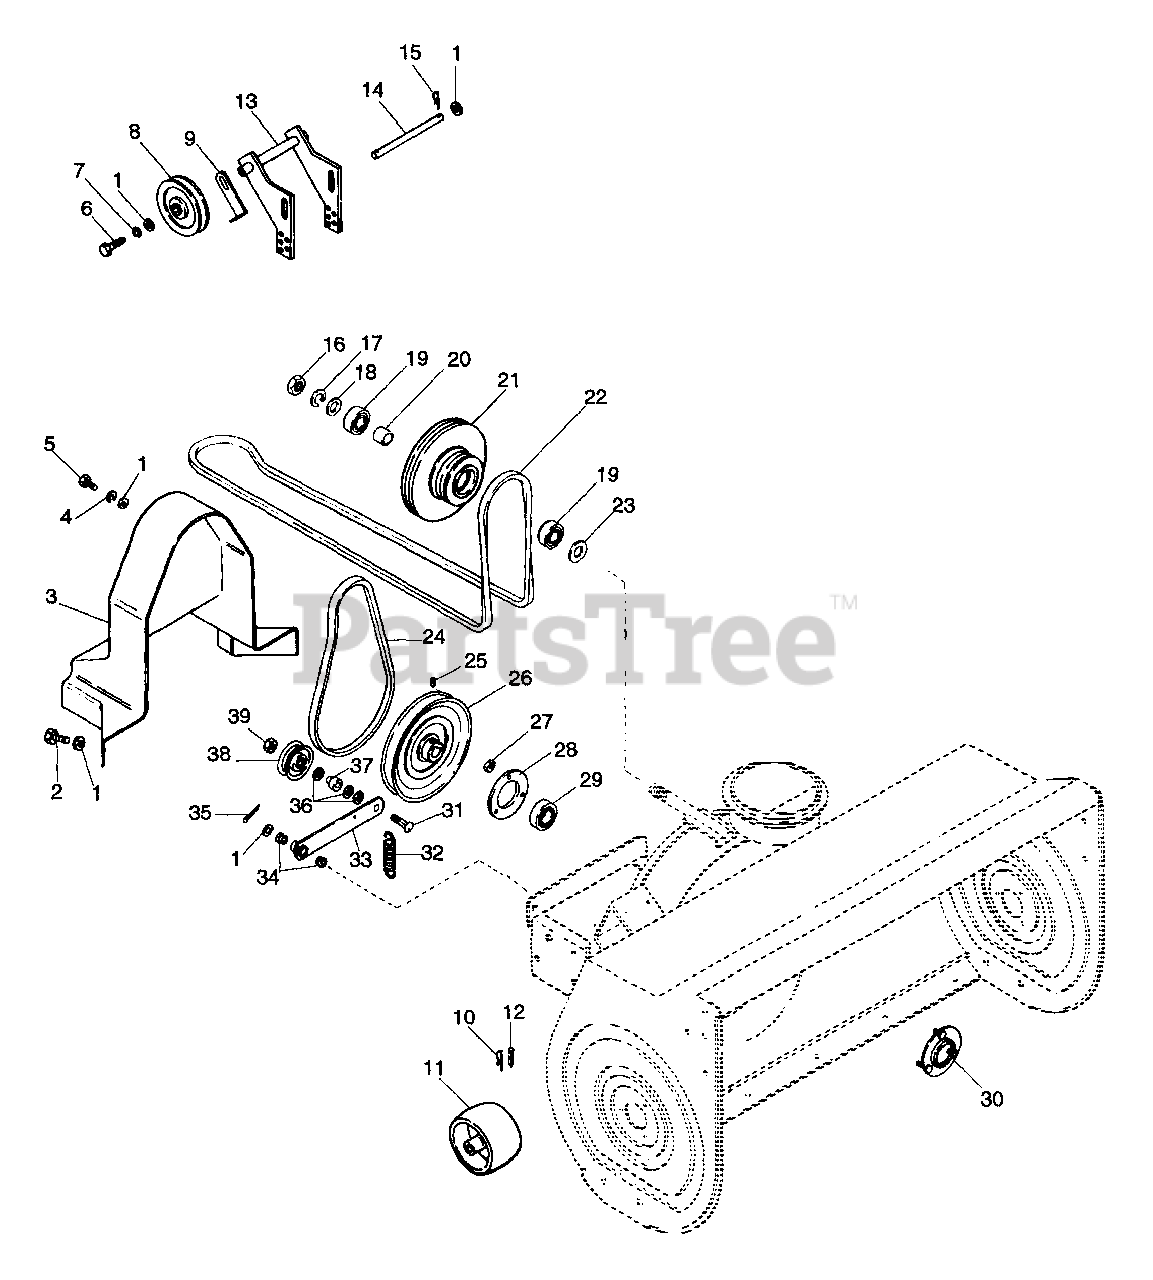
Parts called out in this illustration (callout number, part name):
1	WSHR-FL-STL .382X.812X.062
2	SCR-TAP .375-16X .50 HWH PL TR
3	BELT GUARD
4	WSHR-LK .312X.097 PL HVY
5	BLT-HEX .31-18X.75 PL GR5
6	BLT-HEX .38-16X1.50 PL GR2
7	WSHR-LK .375X.094 MED PL
8	IDLER-V 4.00 X .38 NWHAMSHR
9	BELT RETAINER
10	PIN-HAIR INT .08X.38X1.42 YWZC
12	PIN-COTR .09X.75 PL
13	IDLER BRACKET
15	PIN-HAIR INT .08X.18X1.18
16	NUT-JAM .75-10 PL
17	WSHR-LK-INT .750X.050 MED
18	WSHR-FL-STL .781X1.250X.059 PL
19	BRG-BALL .750X1.781X.61
20	SPACER 1.00 X .770/.760 X .813
22	V-BELT, HA-WRAPPED
23	WSHR-FL-STL .781X1.500X.188
24	V-BELT, HA-COGGED
25	SCR-SET .32-18X.50 SKHCUP OH
26	PLY-V 7.50 X .75 W/KEY SALEM
27	NUT-LK-CTR .250-20 PL
28	BEARING FLANGE
29	BRG-BALL1.0X2.0X.56
30	BEARING FLANGE
31	BLT-RDHDSQNK .38-16X1.50 PL
32	SG-TENS .090X.75X3.50 WLD 34
33	IDLER ARM
34	BSHG-FLG .372X.500X.312X.625NY
35	PIN-COTR .12X.75 PL
36	WSHR-FL-STL .505X.880X.072 PL
37	SPACER -FLANGED .390X.500X.781
38	IDLER
39	NUT-LK-CTR .375-16 GR A PL
